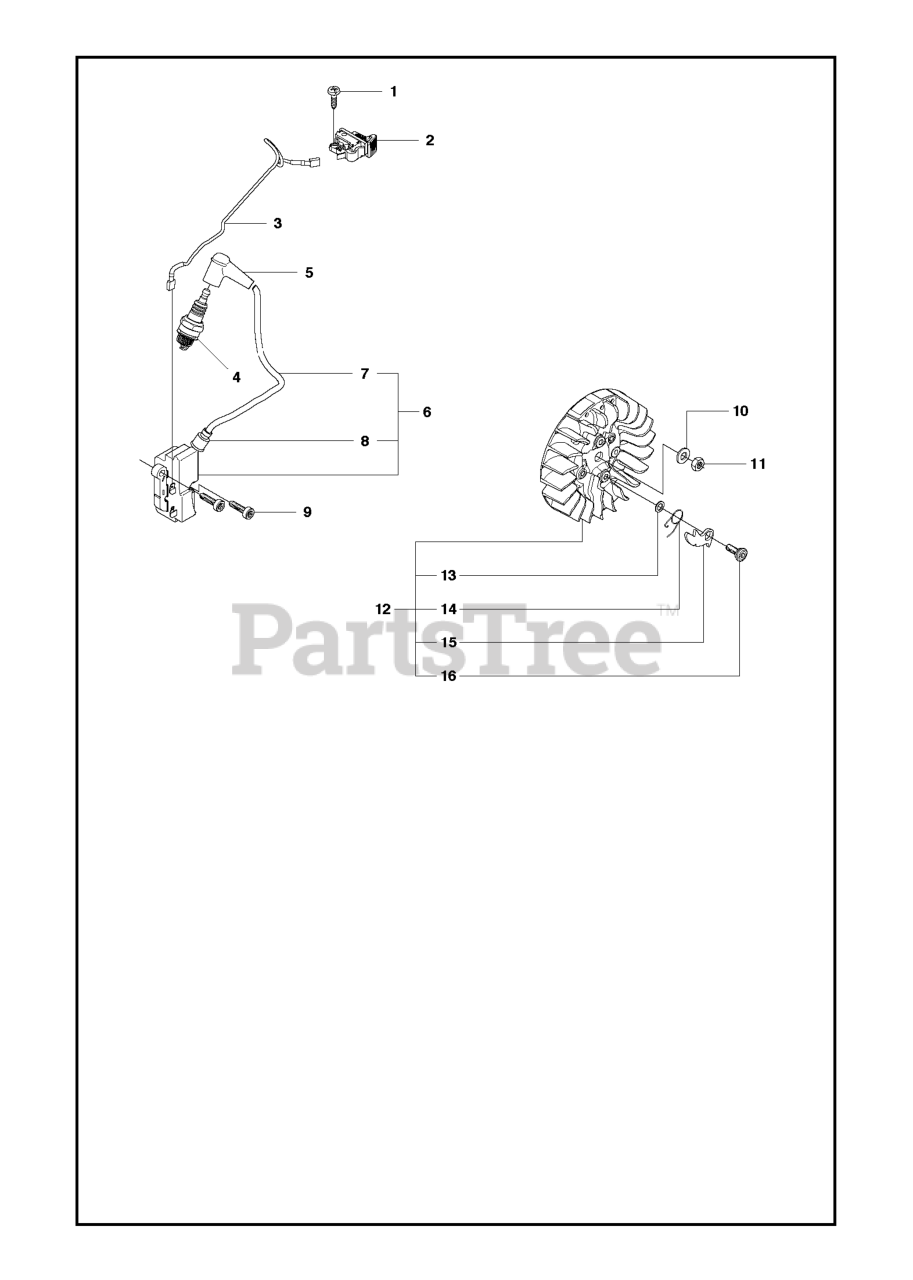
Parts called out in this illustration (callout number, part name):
1	SCREW CITXPANT PW3.5X6.5 T10
2	STOP SWITCH
3	SHORTING LEAD
4	SPARK PLUG M14X1.25 NGK BPMR7A
5	SPARK PLUG CONN. KIT
6	IGNITION MODULE DM51 W.BOOT L=
7	CABLE STOP SWITCH
8	INSULATING CAP
10	WASHER 8.4X16
12	FLYWHEEL
16	SCREW
